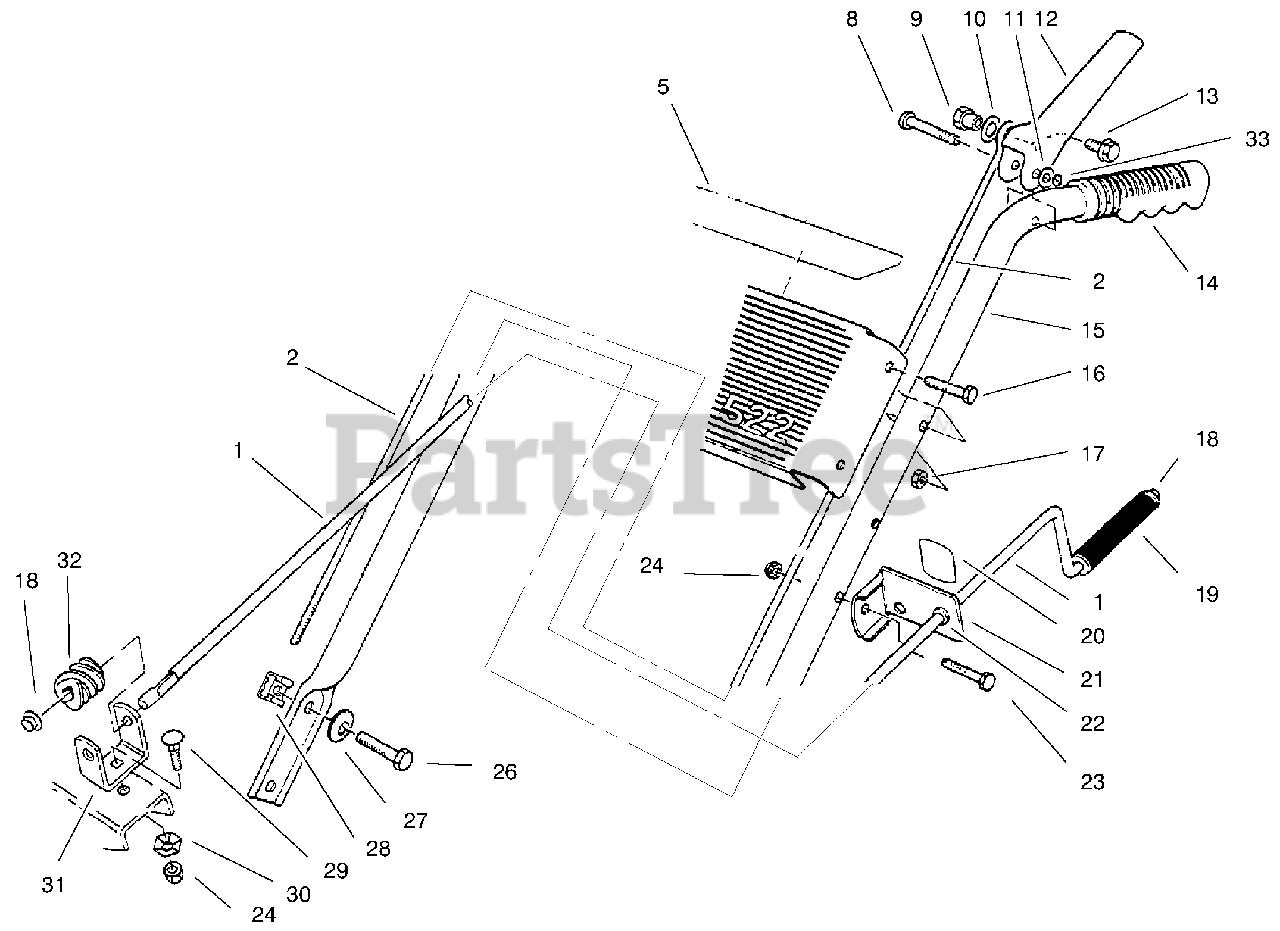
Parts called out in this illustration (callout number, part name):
1	Rod-Chute Control
2	Link-Upper
5	Decal-Escutcheon Back
8	Pin-Control Lever
9	Post-Linkage Mounting
12	Handle-Control
13	Screw-Hex. Flange Hd.
14	Grip-Handle
15	Handle-Left
16	Screw-Hex. Head
17	Nut-Lock
19	Grip-Rod
20	Decal-Chute Direction
21	Bracket-Chute Control (Incl. Ref.# 20 & 22)
22	Nyliner
23	Screw-Hex. Hd.
24	Nut-Lock
26	Screw-Hex. Hd.
27	Washer-Belleville
28	Retainer-Nut
29	Bolt-Carriage
30	Washer-Pyramidal
31	Bracket-Chute Worm
32	Gear-Worm
33	Ring Clip
